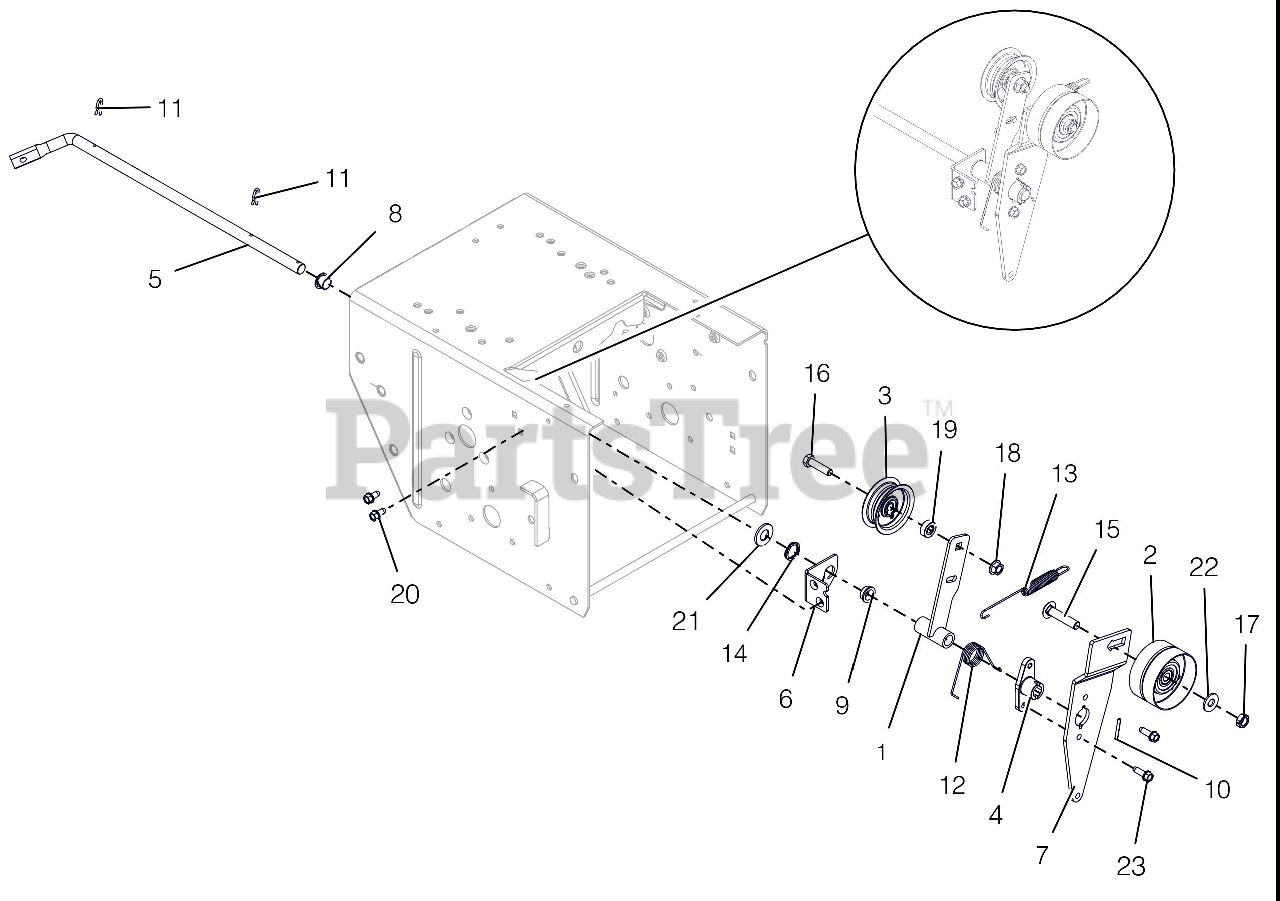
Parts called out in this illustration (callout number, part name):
1	ARM, IDLER-TRACTION
2	IDLER, FLAT-2.75 OD X .375 ID
3	IDLER, FLAT - 2.00"
4	HUB, BRAKE ARM
5	ARM, ATTACHMENT
6	BRACKET, SUPPORT
7	ARM, IDLER-ATTACHMENT
8	BUSHING, POLYLINER-.50 SPLIT
9	BSHG,FLANGE .500X.625X.270X.75
10	PIN-ROLL .125X1.00
11	CLIP, SPRING
12	SG-TORS .067X.88
13	SG-TENS .06X.482X5.35
14	WAVE SPRING .600X.875X.25FH
15	@BLT-RHDSSQNK .38-16X1.75 G5YZ
16	@BLT-HEX .31-18X1.25 GR5 YWZC
17	@NUT-LK-CTR-JAM .375-16 YWZC
18	@NUT-LK-TOP-FLG .31-18 YWZC
19	SPCR, BRG .315X.500X.358X.281
20	SCR-TAP .25-20X.50 HWH TR YWZ
21	@WSHR-FL-STL.531X1.06X.095YWZC
22	@WSHR-FL-STL.38X.875X.083 YWZC
23	SCR-TAP-PM .25-20X.75 TR YWZ
